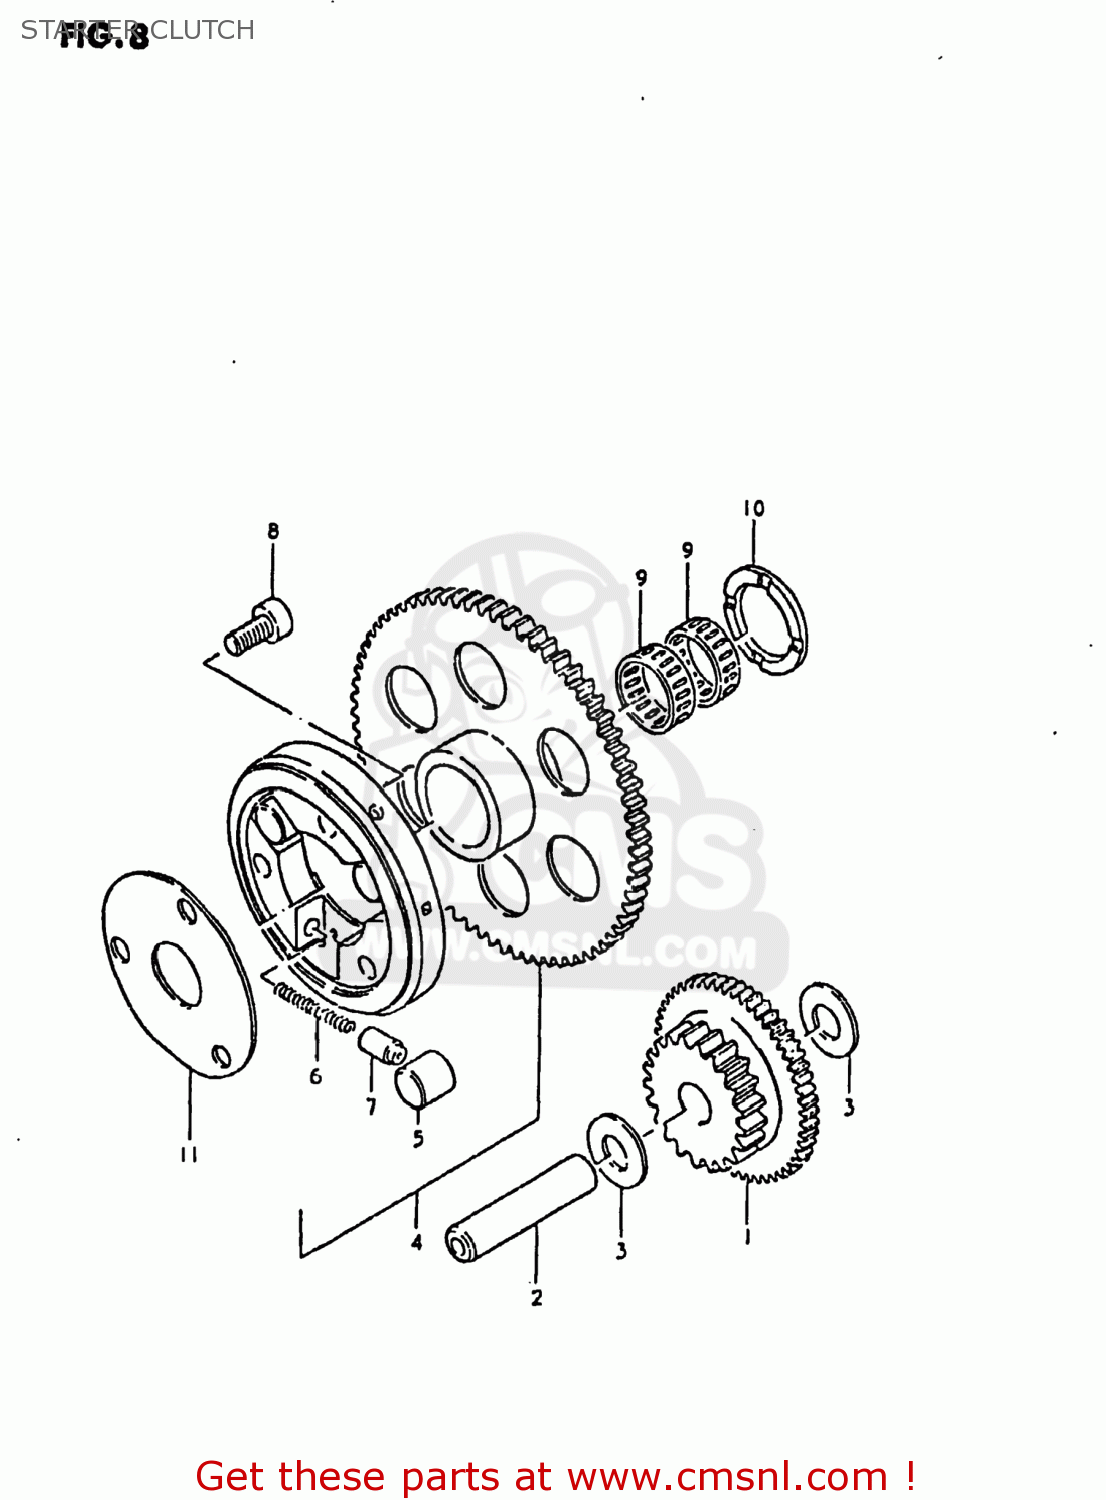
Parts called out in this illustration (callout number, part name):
1	GEAR,STARTER IDLE
2	PIN(7.4X13X56)
3	WASHER(13.3X25X0.85)
4	CLUTCH SET,STARTER
5	PIN(14X13)
6	SPRING
7	PIECE,PUSH
8	BOLT
9	ROLLER BEARING (25X30X9
10	WASHER(25X38X2.5)
11	SHIM,STARTER CLUTCH HUB
